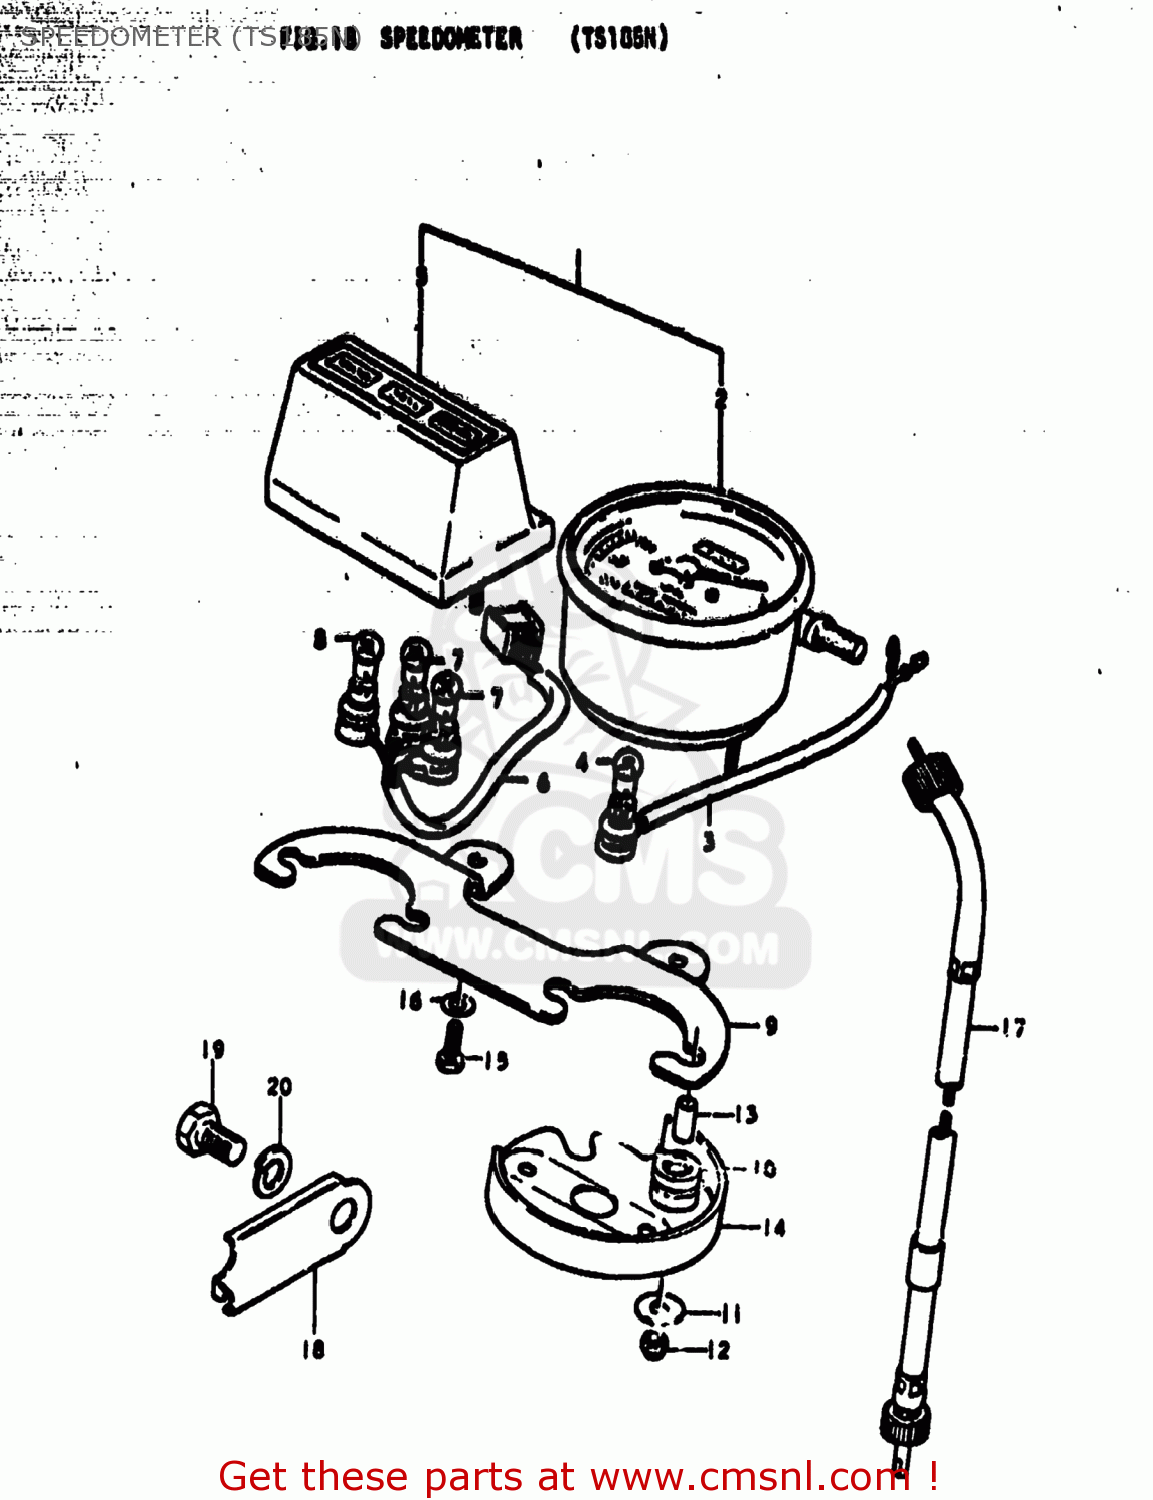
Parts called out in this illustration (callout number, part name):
1	SPEEDOMETER ASSEMBLY
2	SPEEDOMETER ASSEMBLY
3	SOCKET,SPEEDOMETER
4	BULB(6V/3W)
5	CASE,PILOT BULB
6	SOCKET
7	BULB(6V/3W)
8	BULB(6V1.7W,STANLEY,A61A)
9	BRACKET,COMBINATION METER
10	CUSHION,METER
11	WASHER (5.5X16X1.2)
12	NUT
13	SPACER,METER
14	COVER,METER,UNDER
15	BOLT, UPPER
16	WASHER
17	CABLE ASSEMBLY,SPEEDOMETER
19	BOLT 8X12
20	LOCK WASHER
